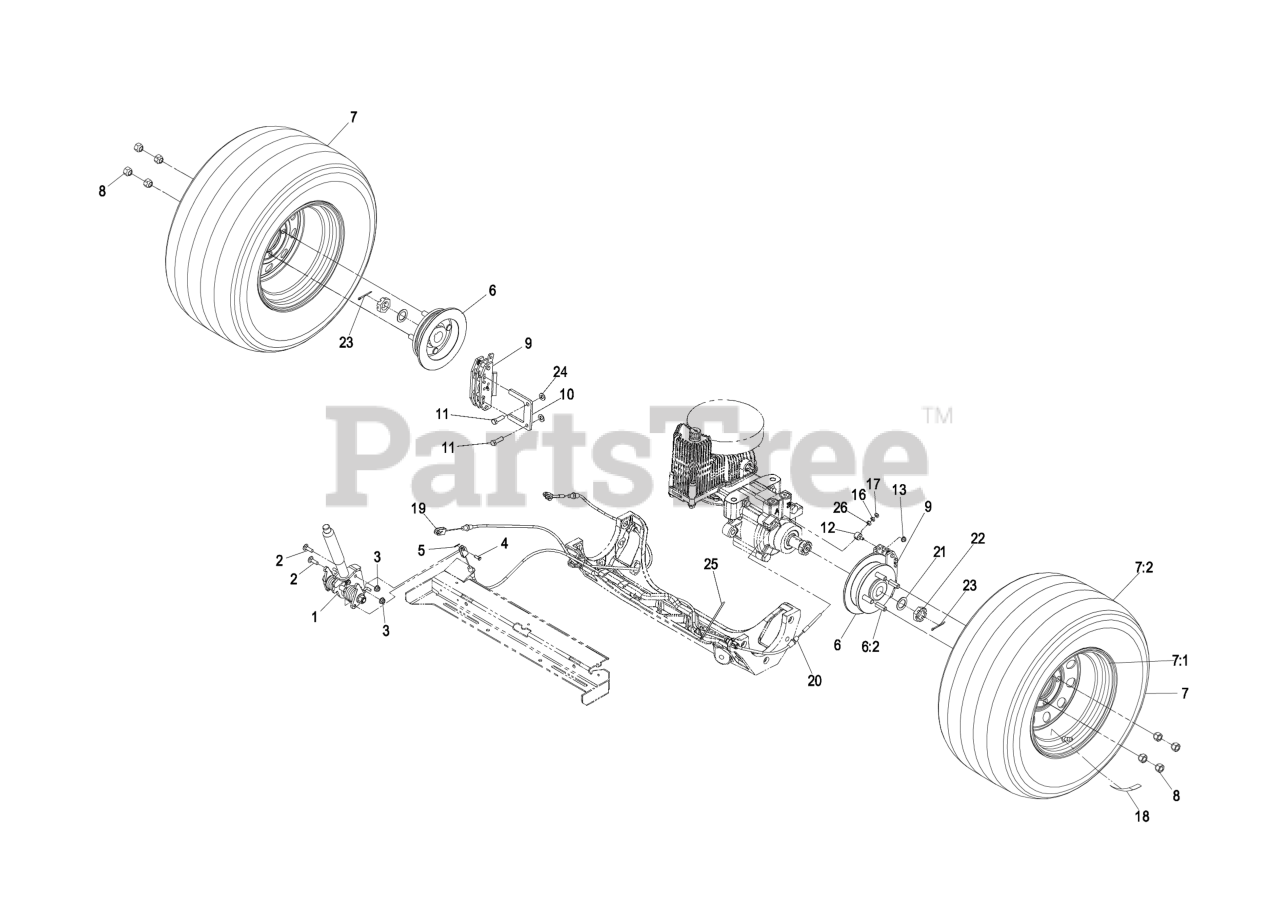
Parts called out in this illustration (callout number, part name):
2	BOLT-CARR
3	NUT-HF, NI
4	PIN-CLEVIS
5	PIN-COTTER
6:2	STUD-WHEEL
7	WHEEL AND TIRE ASM
7:1	RIM ASM
7:2	TIRE
8	NUT-LUG
9	CALIPER-BRAKE
10	PLATE-MOUNT, BRAKE
11	SCREW-HH
16	NUT-JAM
17	NUT-LOCK, NI
18	DECAL-HUB, WHEEL
21	WASHER-SPACER
23	PIN-COTTER
24	WASHER-FLAT
25	TIE-CABLE
26	NUT-HEX
